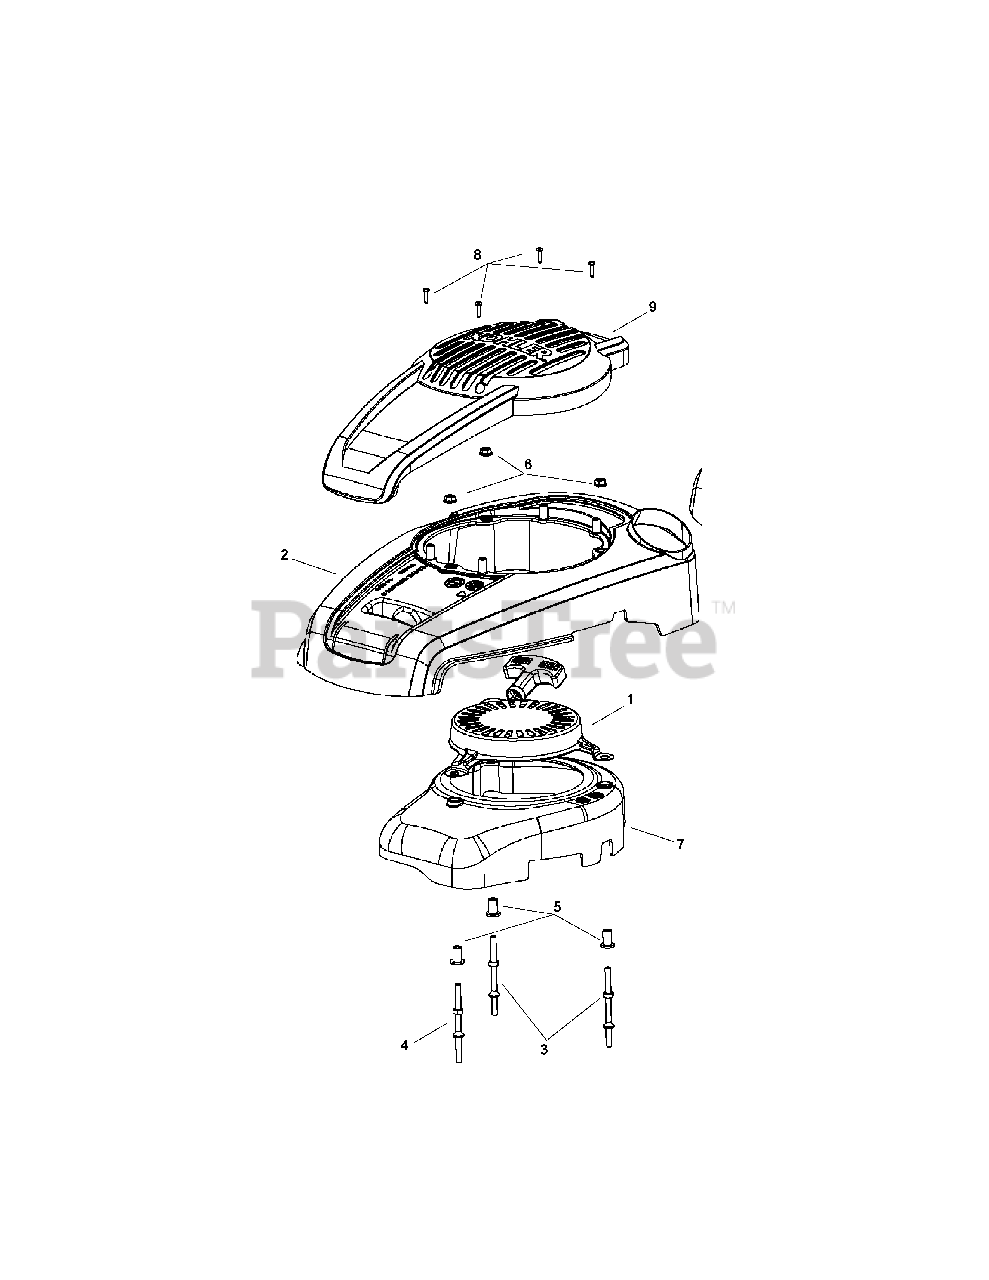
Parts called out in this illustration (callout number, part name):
1	Retractable Starter Assembly
2	Engine Cover, Black
3	Stud
4	Stud
6	Hex Flange Nut, M6
7	Blower Housing
8	Screw, #15 6-Lobe Pan Hd
9	Engine Cover Insert, Black
